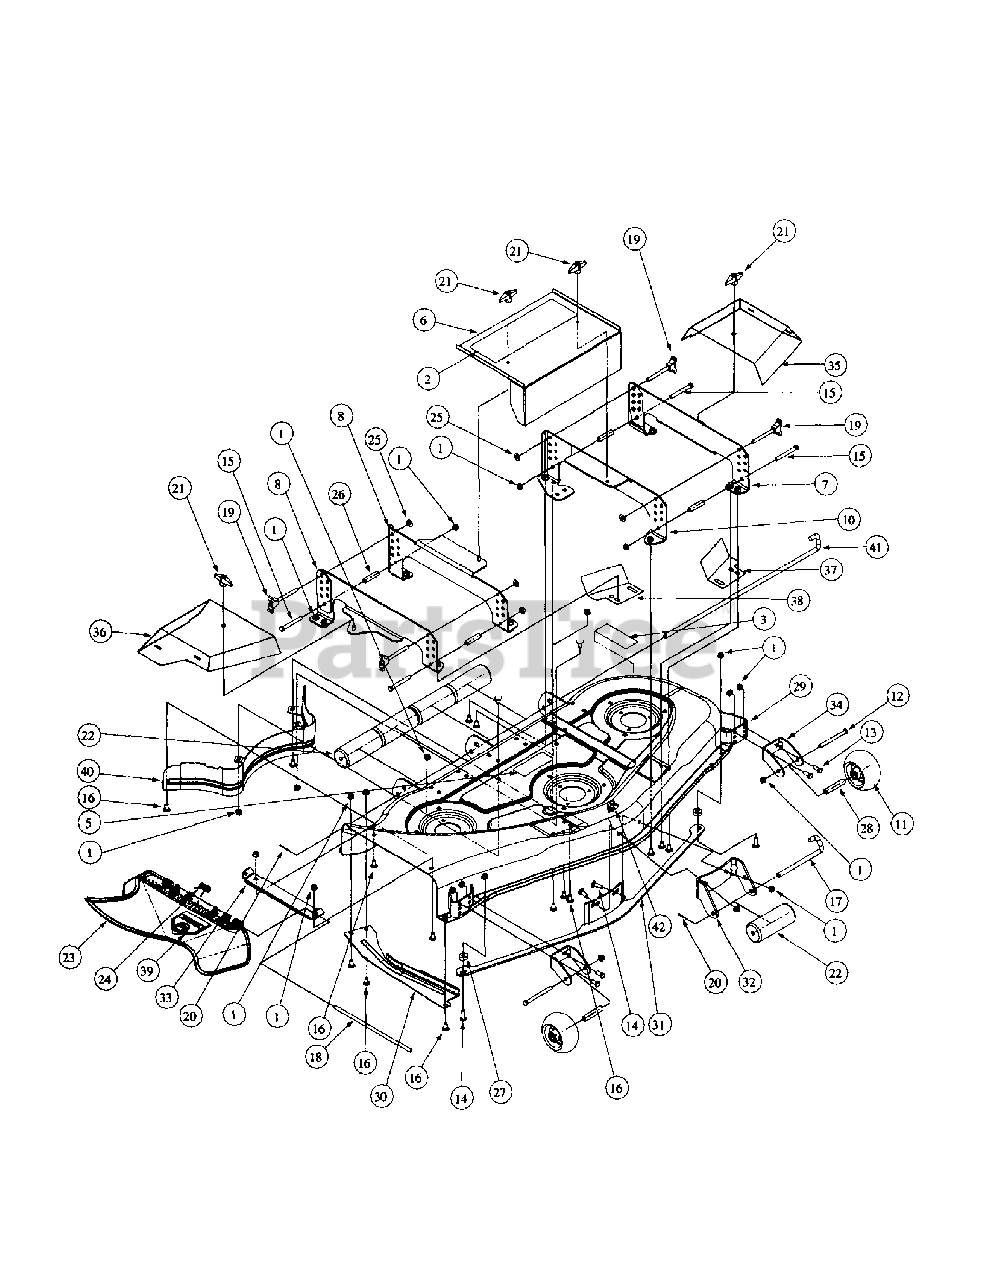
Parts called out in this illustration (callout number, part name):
1	Nut, Hex, 3/8-16 Flange Lock
2	Label MTD Pro
3	Decal, Rotating Blade
4	Decal, Warning Safety
5	Decal, Warning Shield Missing
6	Cover, Belt Center
7	Hanger Assembly, Outer Left Handle
8	Hanger Assembly, Inner Right Handle
8	Hanger Assembly, Outer Right Handle
10	Hanger Assembly, Inner Left Handle
11	Wheel, Complete, 5.00 Diameter
12	HHCS, 3/8-16, 4.25
13	HHCS, 3/8-16, .88
14	Carriage Screw, 3/8-16 x 1.25
15	HHCS, 3/8-16, 3.25
16	Carriage Bolt, 3/8-16 x .75 LG
17	Roller Pin, 1/2 Diameter x 7.31 LG
18	Pin Hinge, .375 x 12.93
19	Pin, 3/8 Dia.
20	Cotter Pin, 1/8 x 1.0
21	Knob Assembly, Wingnut 5/16-18
22	Front Roller
23	Deflector Chute
24	Torsion Spring
25	Flat Washer, .385 ID x.870 OD x.092
26	Spacer, Stop Deck
27	Spacer, .406 ID x 1.00 OD x .38
28	Spacer Wheel
29	Mower Deck Assembly
30	Weldment, Guard Assembly
31	Weldment Front Bar 48"
32	Front Roller Bracket
33	Mounting Bracket, Chute
34	Castor Bracket
35	Belt Cover, Left Handle, 48"
36	Belt Cover, 48" Deck R.H.
37	Filler Plate, Left Hand
38	Filler Plate, Right Hand
39	Decal, Danger, Hands and Feet
40	Baffle, Right Rear, Inner 48" Deck
41	Roller Pin
42	Label, MTD Pro 48
